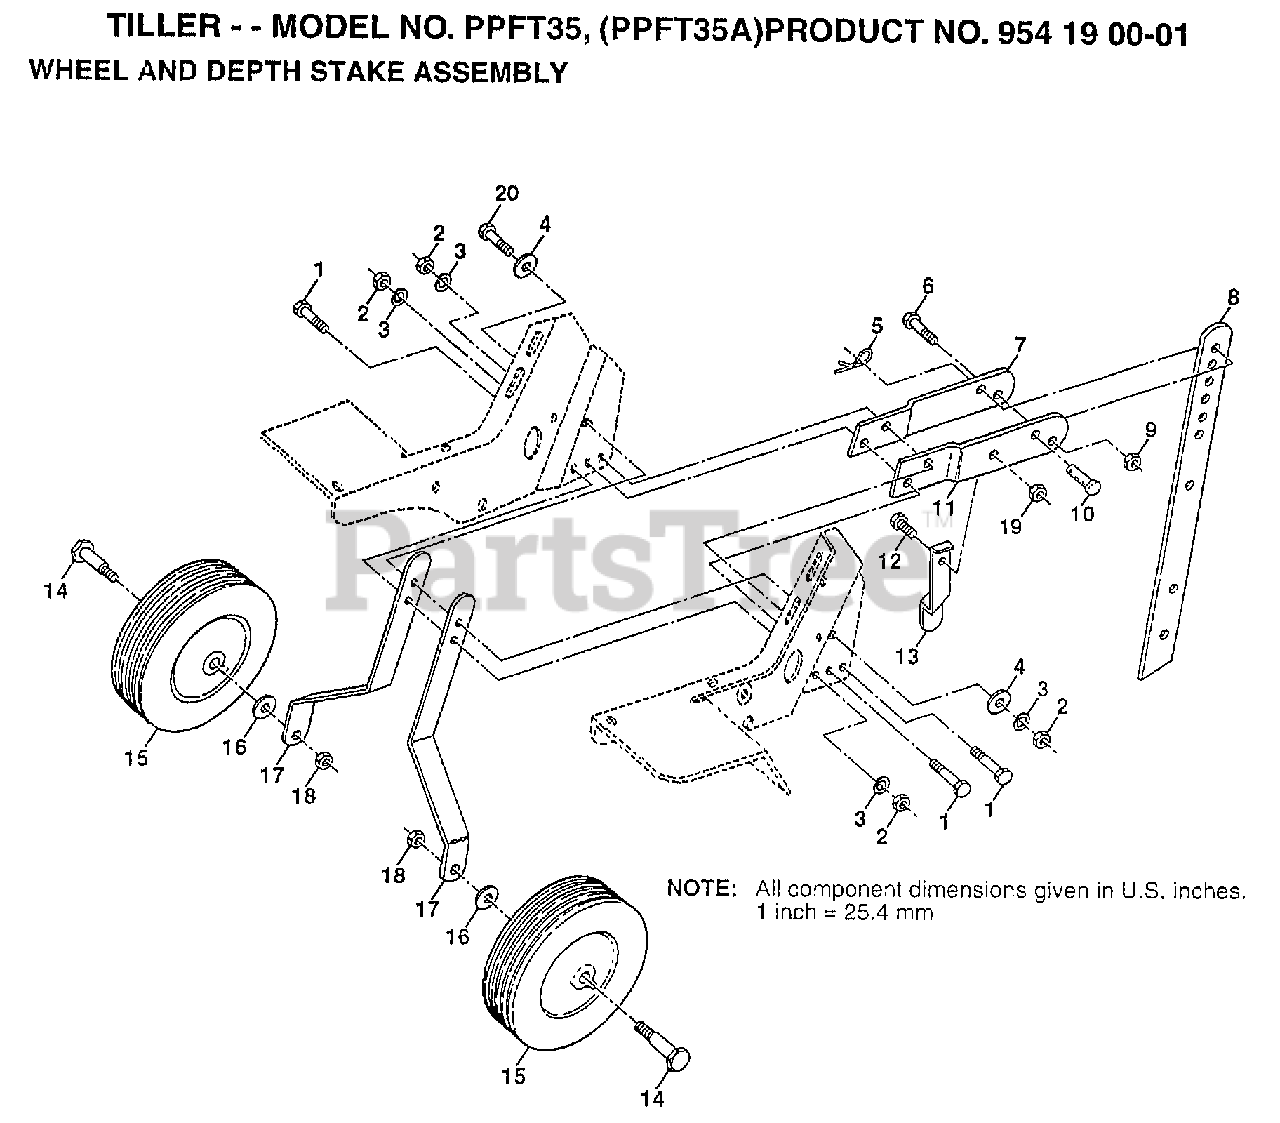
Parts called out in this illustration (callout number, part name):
1	BOLT, HEX 5/16-18 X 1-1/4
4	WASHER 3/8 X 7/8 X 14 GA.
6	BOLT, FIN, HEX 3/8-16 X 1-3/4
9	LOCKNUT
12	BOLT, HEX 5/16-18 X 3/4
16	WASHER 13/32 X 13/16 X 11 GA.
18	NUT, CROWNLOCK 3/8-16
19	LOCKNUT
20	BOLT, HEX 5/16-18 X 1-1/2
